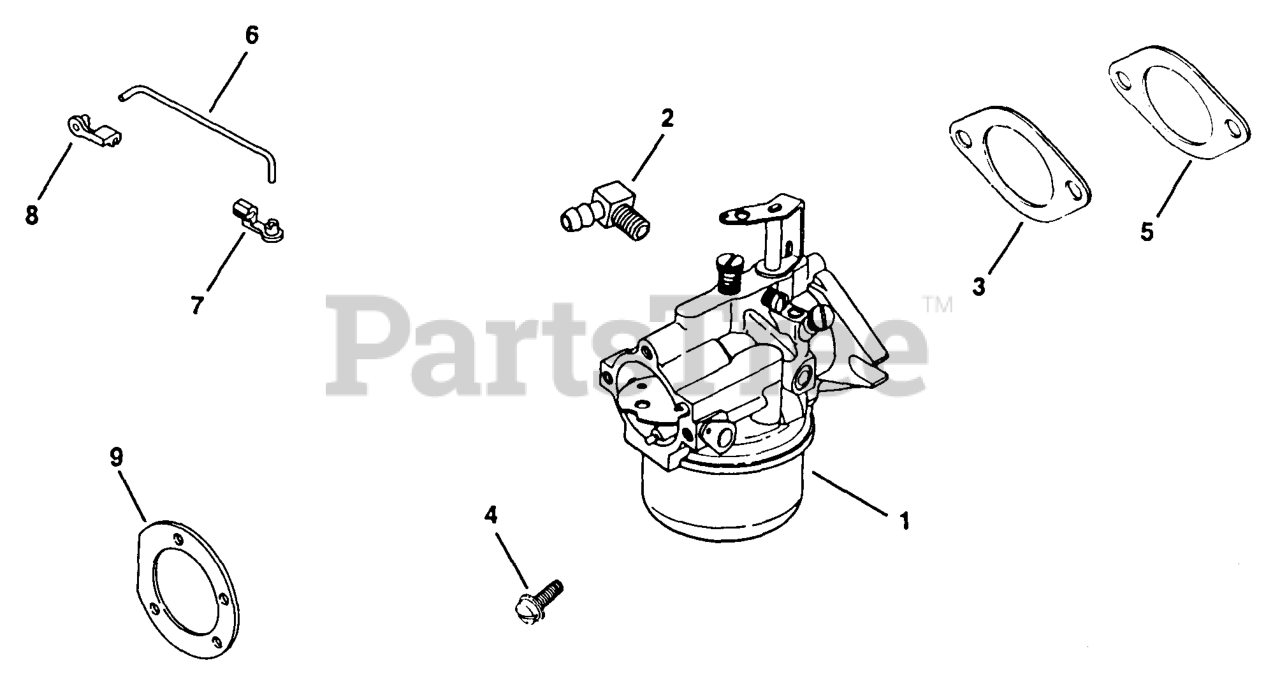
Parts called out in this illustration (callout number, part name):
1	CARBURETOR - USE 47 853 09
1	KIT, CARBURETOR W/LINKAGE - DISCONTINUED
1	CARBURETOR - USE 47 853 25
1	KIT, CARBURETOR
2	CONNECTOR, 90 DEG. HOSE
3	GASKET/SPACER, CARBURETOR
4	SCREW, SLT HD 5/16-18X1" - DISCONTINUED
